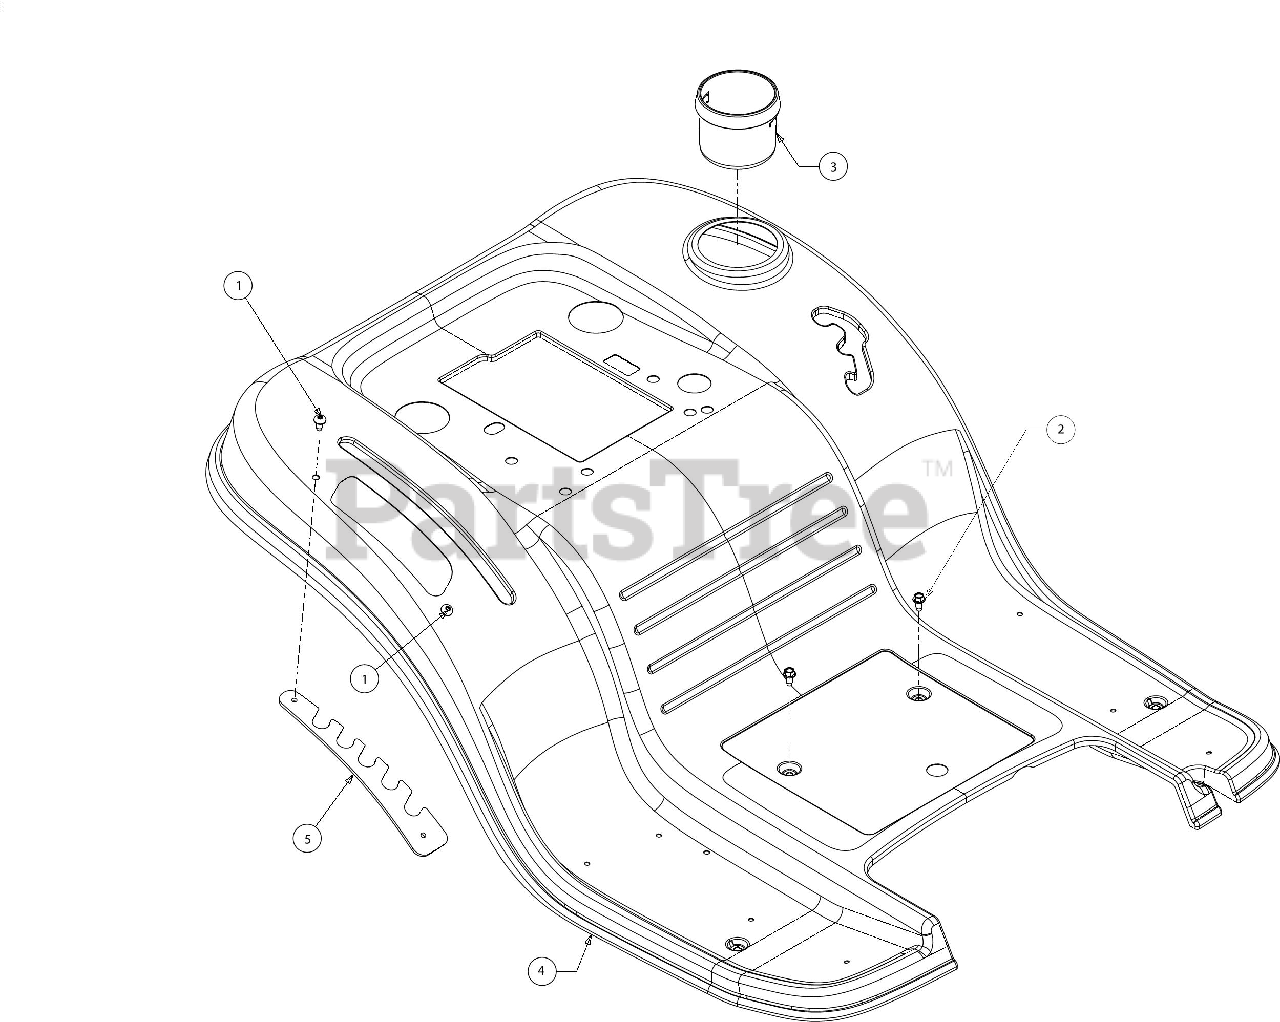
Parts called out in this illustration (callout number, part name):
1	SCREW 1/4-20 X .5
2	SCREW 1/4-20 X.500
3	CUP HOLDER
